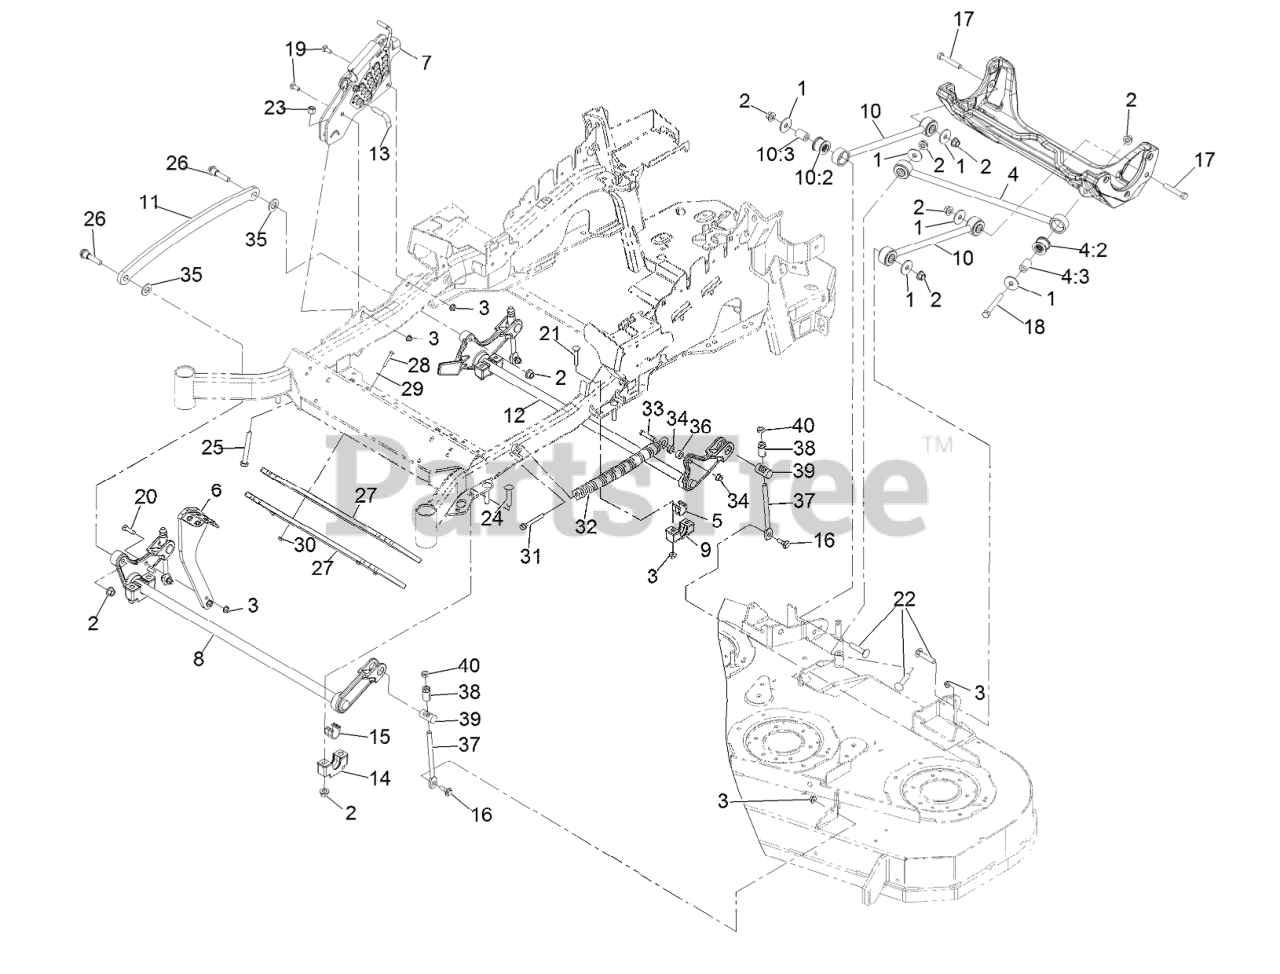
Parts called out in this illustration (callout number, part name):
1	WASHER-THRUST
2	Nut-Lock 1/2-13
3	NUT-HF, NI
4	PANHARD ROD ASM
4:2	BUSHING-SUSPENSION, RUBBER
5	BEARING-CROSS SHAFT, REAR
6	LEVER-FOOT
7	HOC ASM
8	DECKLIFT-FRONT
9	SUPPORT-CROSS SHAFT, BEARING REAR
10	DECK STRUT ASM
10:2	BUSHING-SUSPENSION, RUBBER
11	LINK-LIFT, DECK
12	LIFT-DECK, REAR
13	PIN-HOC
14	SUPPORT-CROSS SHAFT, BEARING
15	BEARING-CROSS SHAFT, FRON
16	SCREW-SHOULDER, HHF
17	SCREW-HH
18	SCREW-HH
19	BOLT-CARR
20	SCREW-CARR
21	Bolt-Carriage 3/8-16 X 2 1/4
22	SCREW-CARR
23	NUT-LOCK, NI
24	Bolt-Carriage 1/2-13 X 2 1/2 Spl Neck
25	BOLT-TAP
26	SCREW-HHF, SHOULDER
31	BOLT-SHOULDER
32	SPRING-EXTENSION
33	SCREW-HH
35	WASHER-FLAT
37	LINK-ADJUSTER, DECK LIFT
38	ADJUSTER-LIFT, DECK
39	TRUNNION
40	NUT-JAM
